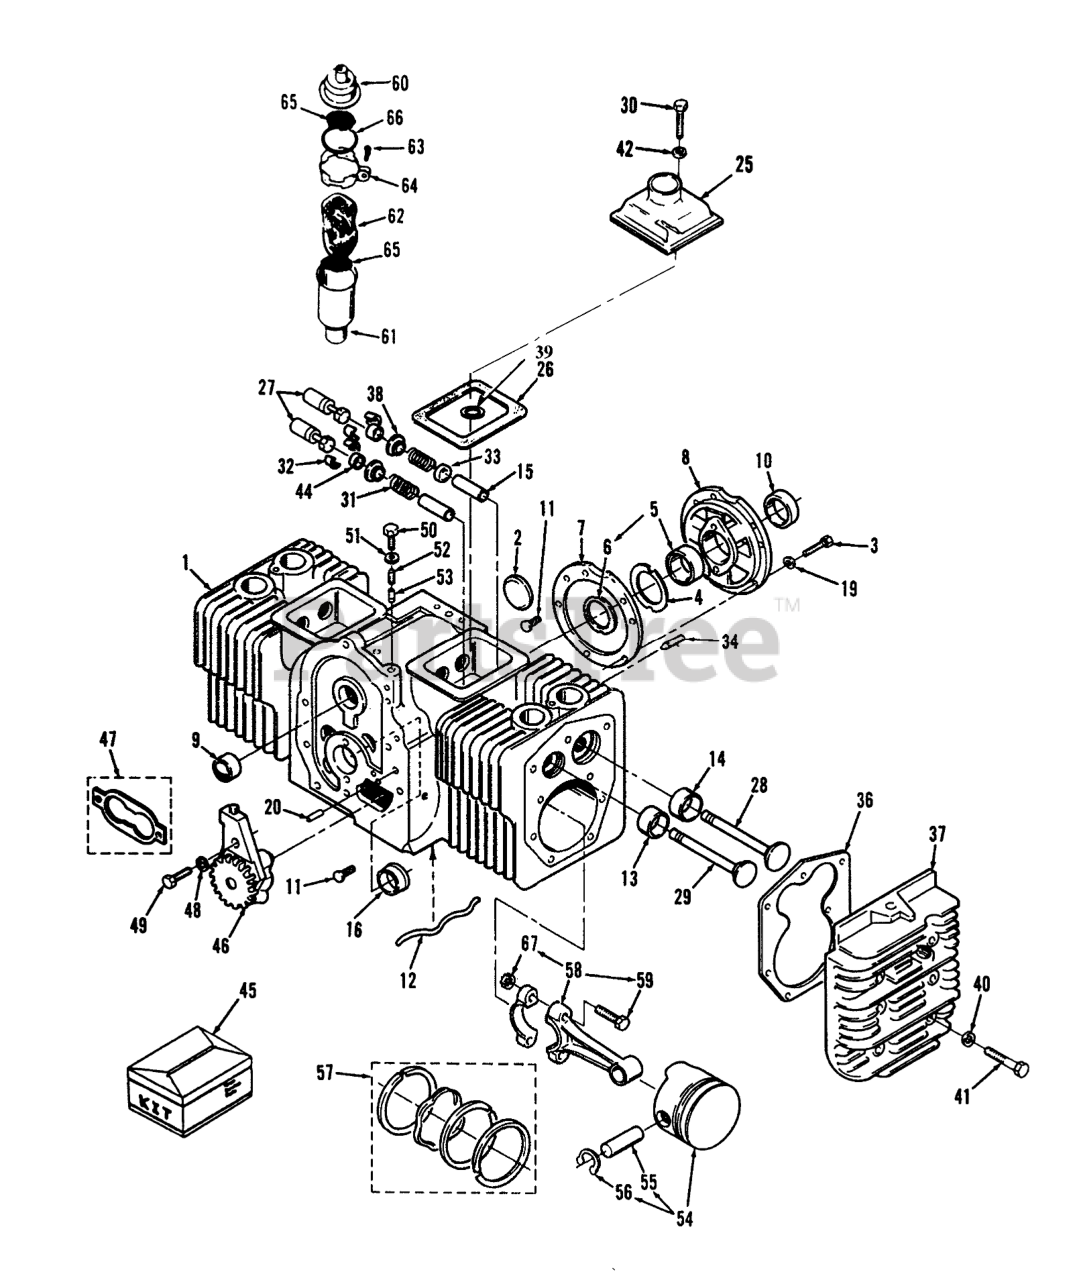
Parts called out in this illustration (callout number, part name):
1	CYLINDER BLOCK
2	Plug
3	Bolt 3/8-16x 1-1/4
5	Bearing-Crankshaft, Rear (Includes Thrust Washer)
6	Thrust Washer
7	GASKET
8	PLATE-BEARING, REAR
9	Camshaft Brg
10	Oil Seal
11	Screw
12	Oil Tube
13	Insert-Valve Seat, Exhaust
14	Insert-Valve Seat, Intake
15	Guide-ExhaustValve
16	Bearing-Crankshaft, Front, Flanged
19	Washer
20	Pin
25	Cover-Valve
26	GASKET
27	Tappet-Valve
28	Intake Valve
29	Exhaust Valve
30	HHCS 1/4-20 X 1 3/4
31	Spring
32	VALVE SPRING LOCK
33	Seal
34	Screw
36	Gasket
37	HOUSING CYL RH
38	Washer
39	Washer
40	Washer
41	Bolt
42	Washer
44	VALVE CAP
45	Kit-Gasket
46	Oil Pump
47	GASKET KIT
48	Washer
49	SCREW - CAP HEX HEAD
50	Bolt
51	Washer
52	Spring
53	Piunger
54	Piston (Includes Pin & Retaining Rings)
55	Pin-Piston
56	Retaining Ring
57	Kit-Ring, Piston
58	Rod-Connecting (Includes Bolt & Nut)
59	Rod Bolt
60	BREATHER-CAP AND VALVE
61	TUBE-BREATHER
62	FILTER
63	SCREW-TAPPING, ROUND HEAD
64	Clamp
65	SCREEN-BREATHER TUBE
66	SEAL - O-RING
67	Nut
